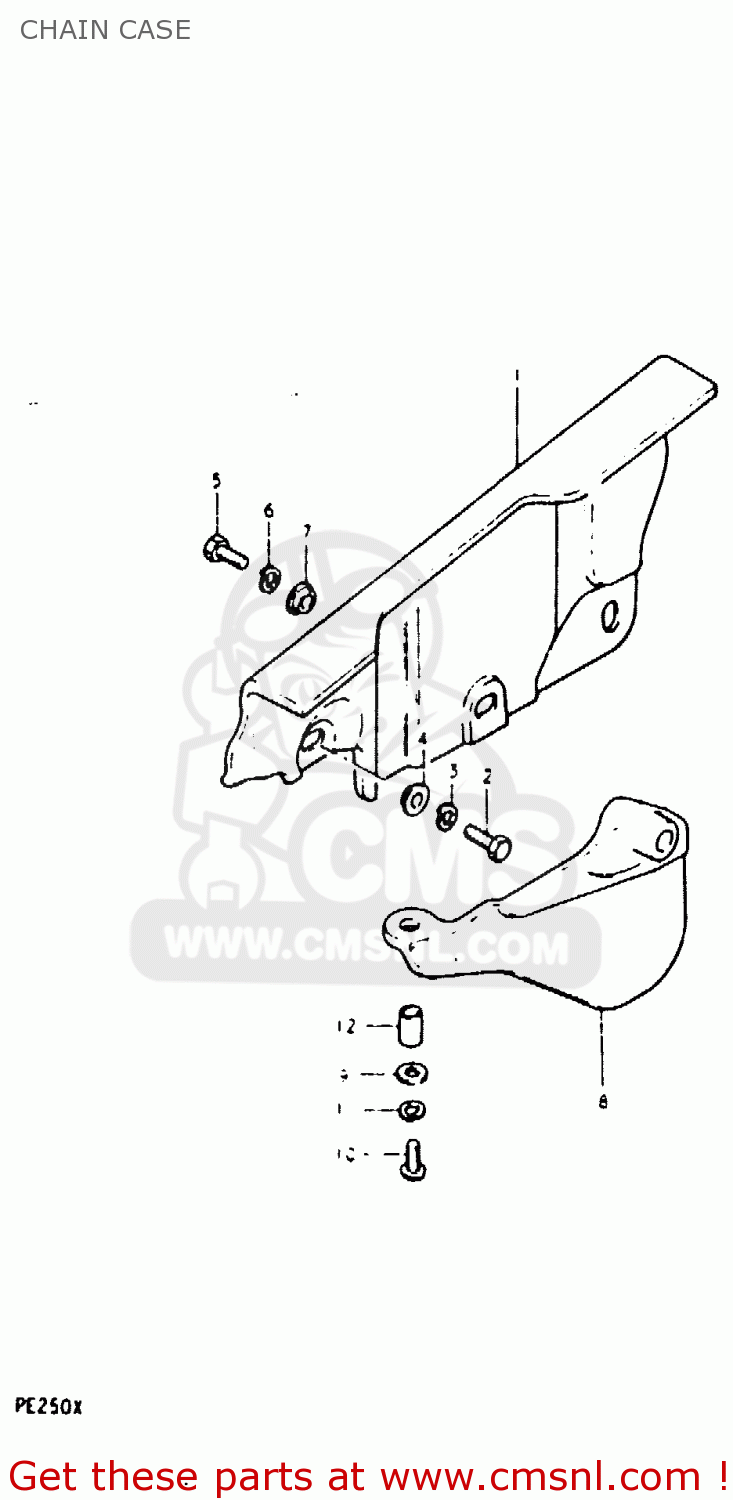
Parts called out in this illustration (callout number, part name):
1	CASE,CHAIN
2	BOLT, UPPER
3	LOCK WASHER
4	WASHER(6.5X18X1)
5	BOLT
6	LOCK WASHER
7	WASHER
8	RUBBER,CHAIN CASE,LOWER
9	WASHER(6.5X18X1)
10	SCREW 6X12
11	LOCK WASHER
12	SPACER (6.1X8X5.2)
